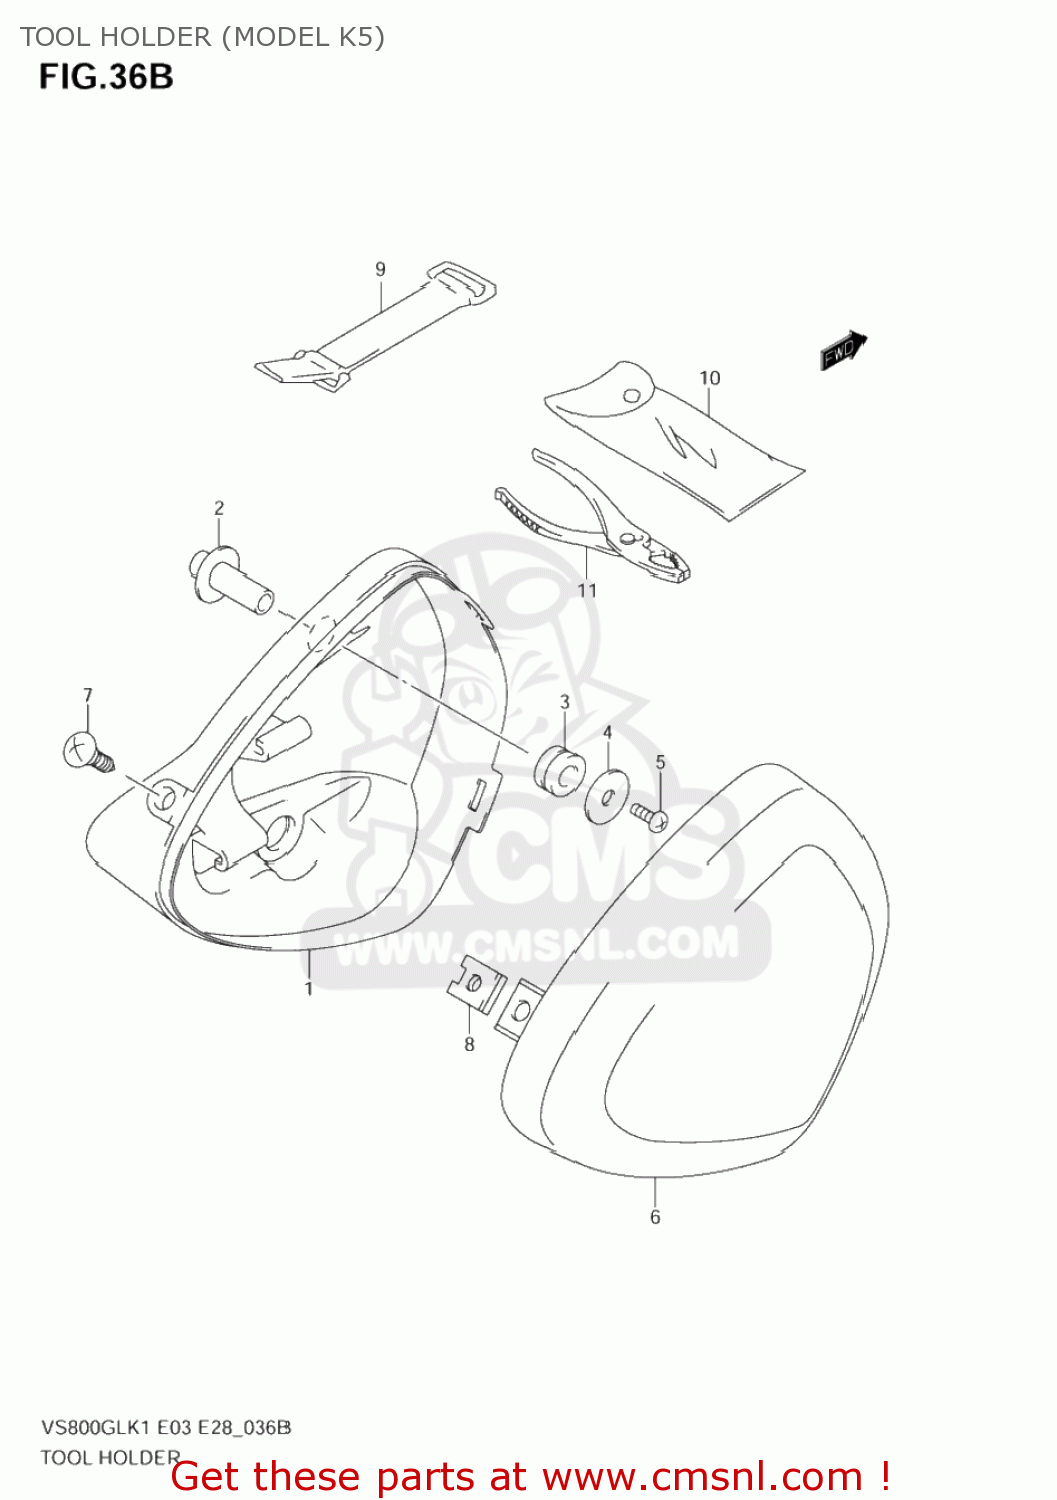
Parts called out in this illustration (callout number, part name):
1	BOX, LUGGAGE V
2	SPACER
3	CUSHION
4	WASHER (6.5X22X1.6)
5	SCREW
6	CAP,TOOL HOLDER
7	SCREW(6X23)
8	NUT
9	BAND
10	TOOL ASSY
11	PLIER(150)
